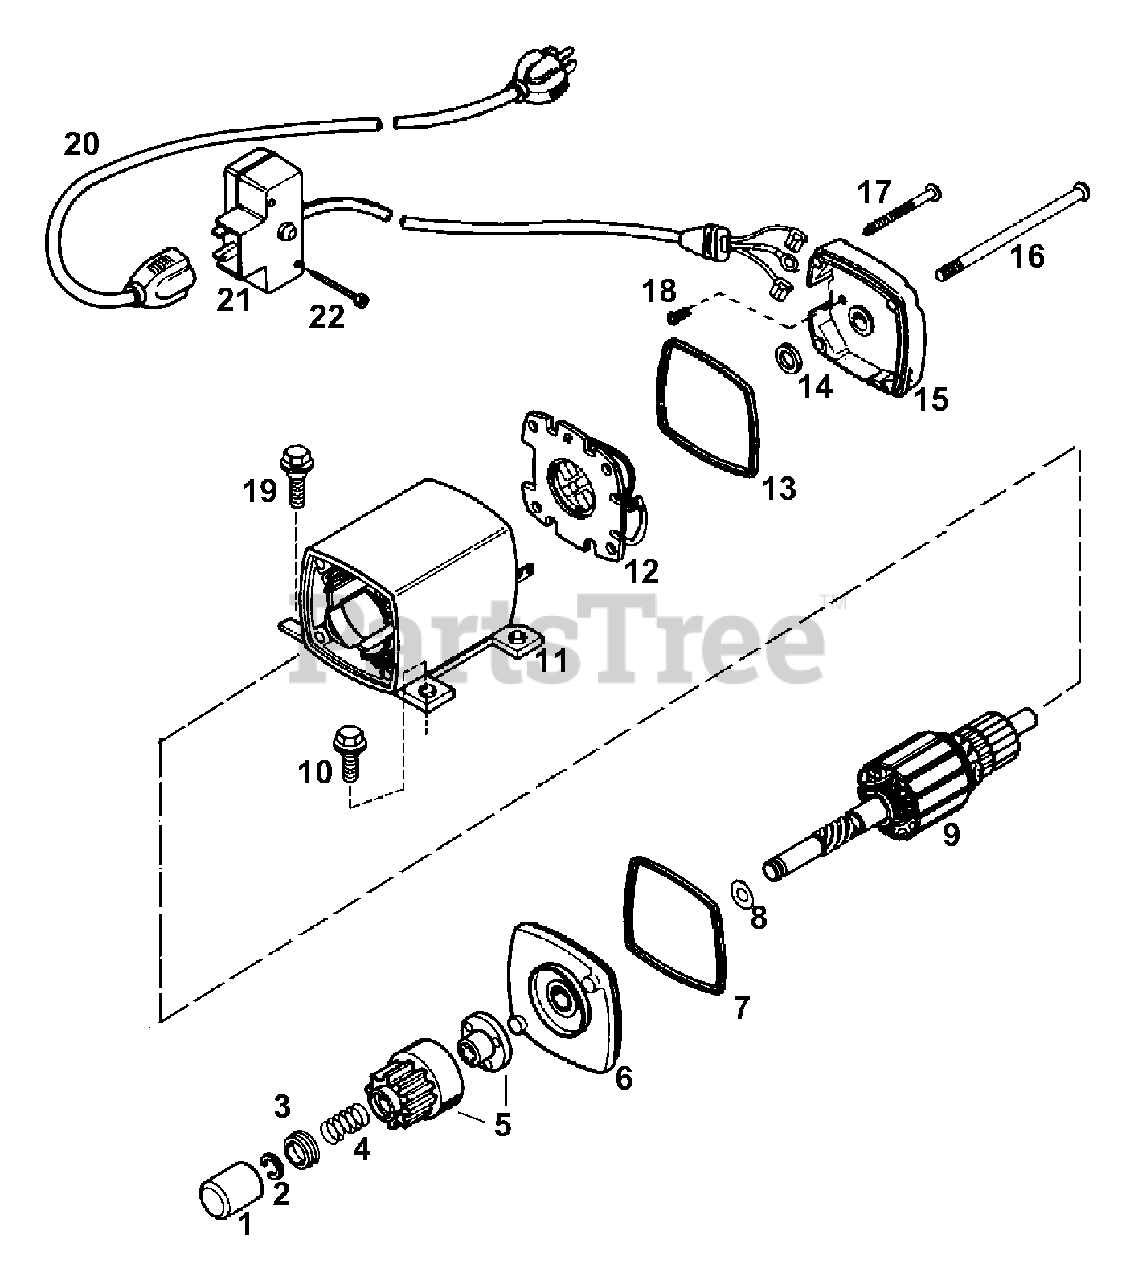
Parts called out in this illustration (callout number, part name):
1	Dust Cover
2	Retainer Ring
3	Spring Retainer
4	Anit-drift Spring
5	Gear & Nut
6	Drive End Cap Ass'y
8	Thrust Washer
10	Screw, Torx T-30, 1-4/20 x 1/2"
11	Housing Ass'y
12	Brush Card Ass'y
14	Thrust Washer
15	Communicator End Cap Ass'y
16	Case Bolt
17	Ground Screw
18	Ground Screw
19	Screw, 1/4-20 x 1/2"
20	Extension Cord (10'6)
21	Switch Box Ass'y
22	Screw, 12-16 x 5/8"
